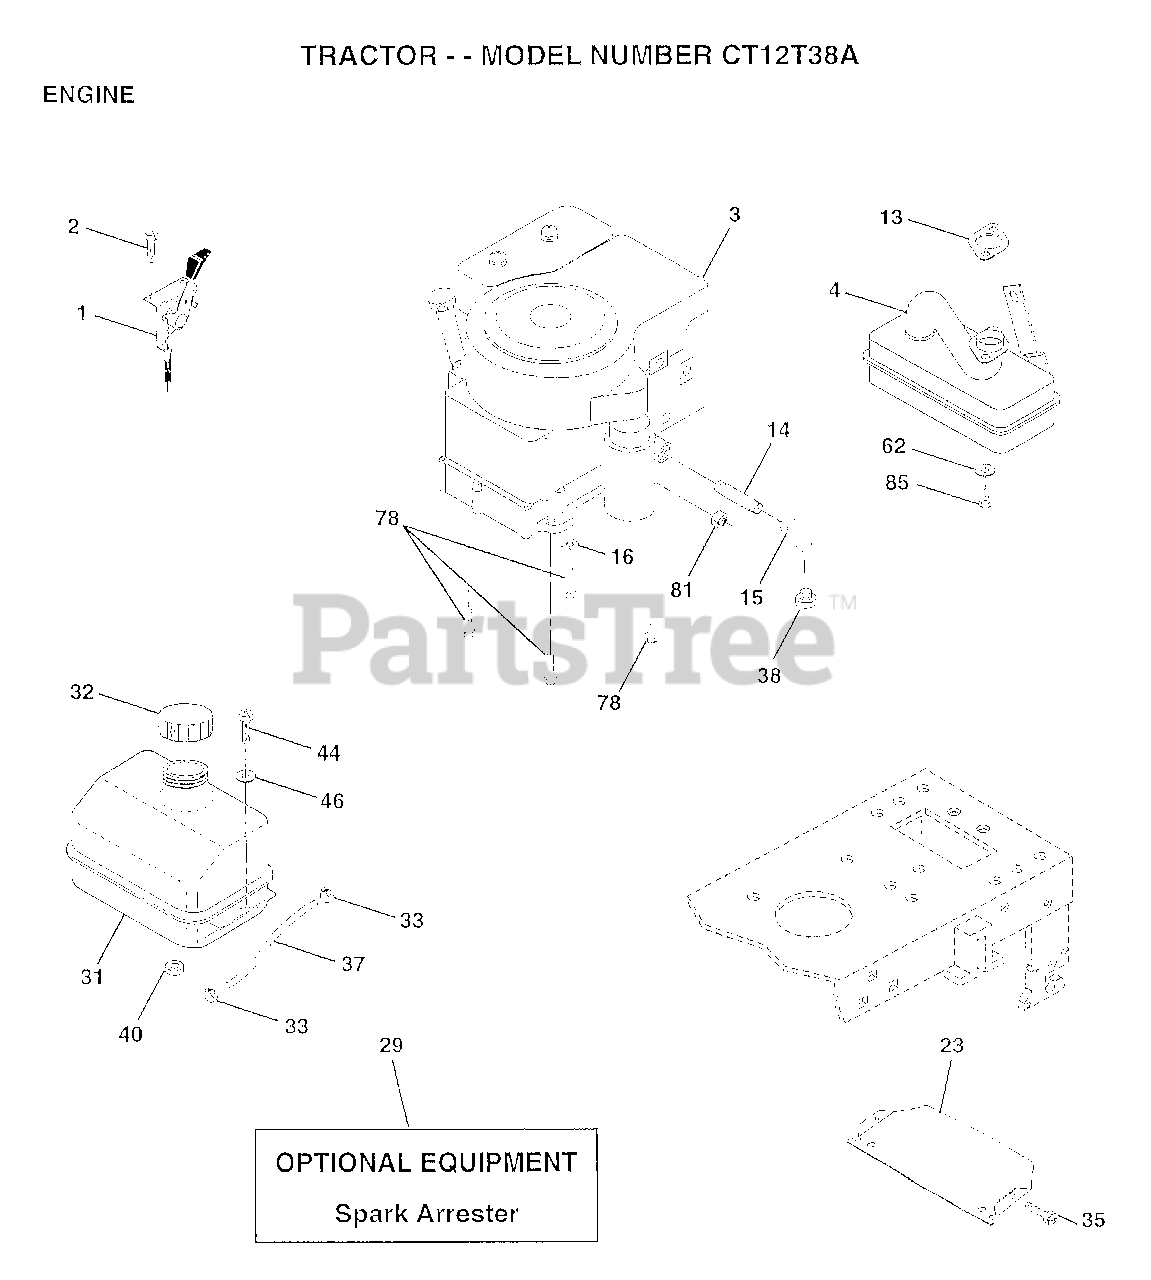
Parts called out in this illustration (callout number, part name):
1	THROTTLE CONTROL
2	SCREW LT
4	MUFFLER TEC. 13HP
13	GASKET ENG 1 313 LD TIN PLATED
14	PIPE NIPPLE LT
15	ELBOW
16	LOCKWASHER
23	SHIELD-HEAT
31	TANK.FUEL.LT.
32	CAP ASM FUEL
33	HOSE CLAMP
35	SCREW
37	LINE FUEL
44	SCREW HEX CRT
46	WASHER
62	LOCKWASHER
78	SCREW
81	NUT
85	SCREW HEX HD CAP
